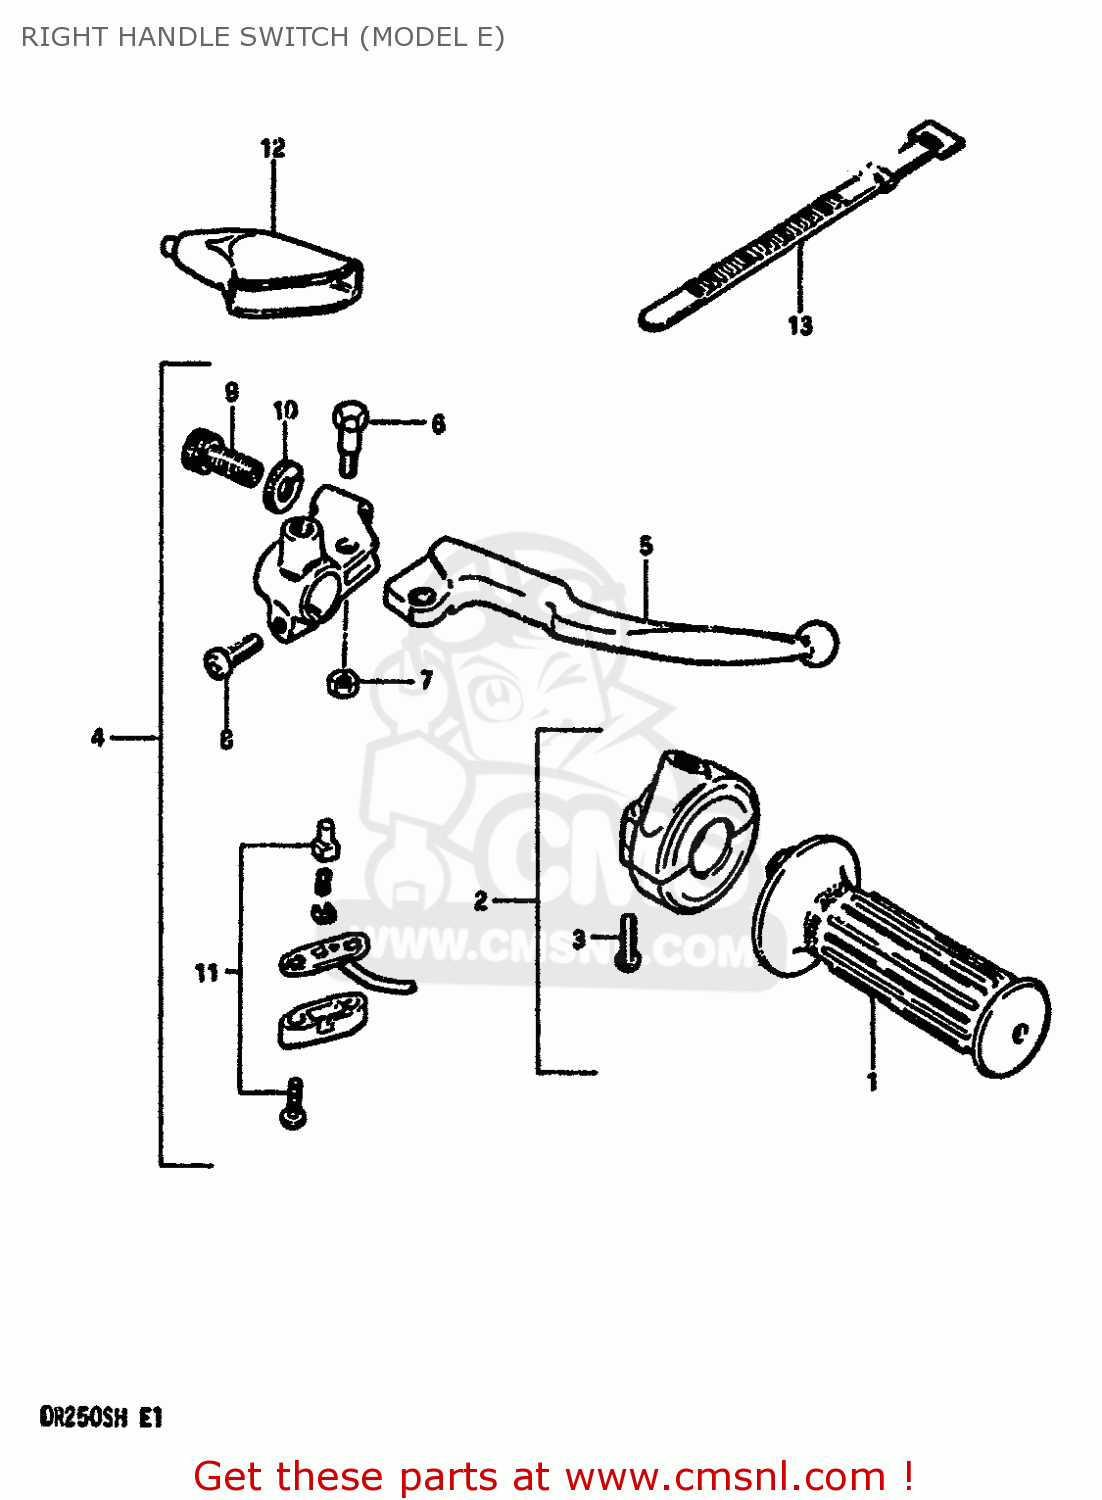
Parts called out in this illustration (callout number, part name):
1	GRIP,THROTTLE
2	CASE ASSY,THROTTLE
3	SCREW 5X20
4	LEVER ASSEMBLY,BRAKE
5	LEVER,BRAKE
6	BOLT,LEVER
7	NUT 6MM
8	SCREW
9	ADJUSTER,CABLE
10	NUT,CABLE ADJUSTER
11	SWITCH ASSY,STOP
12	COVER,CLUTCH LEVER
13	CLAMP(L:120)
